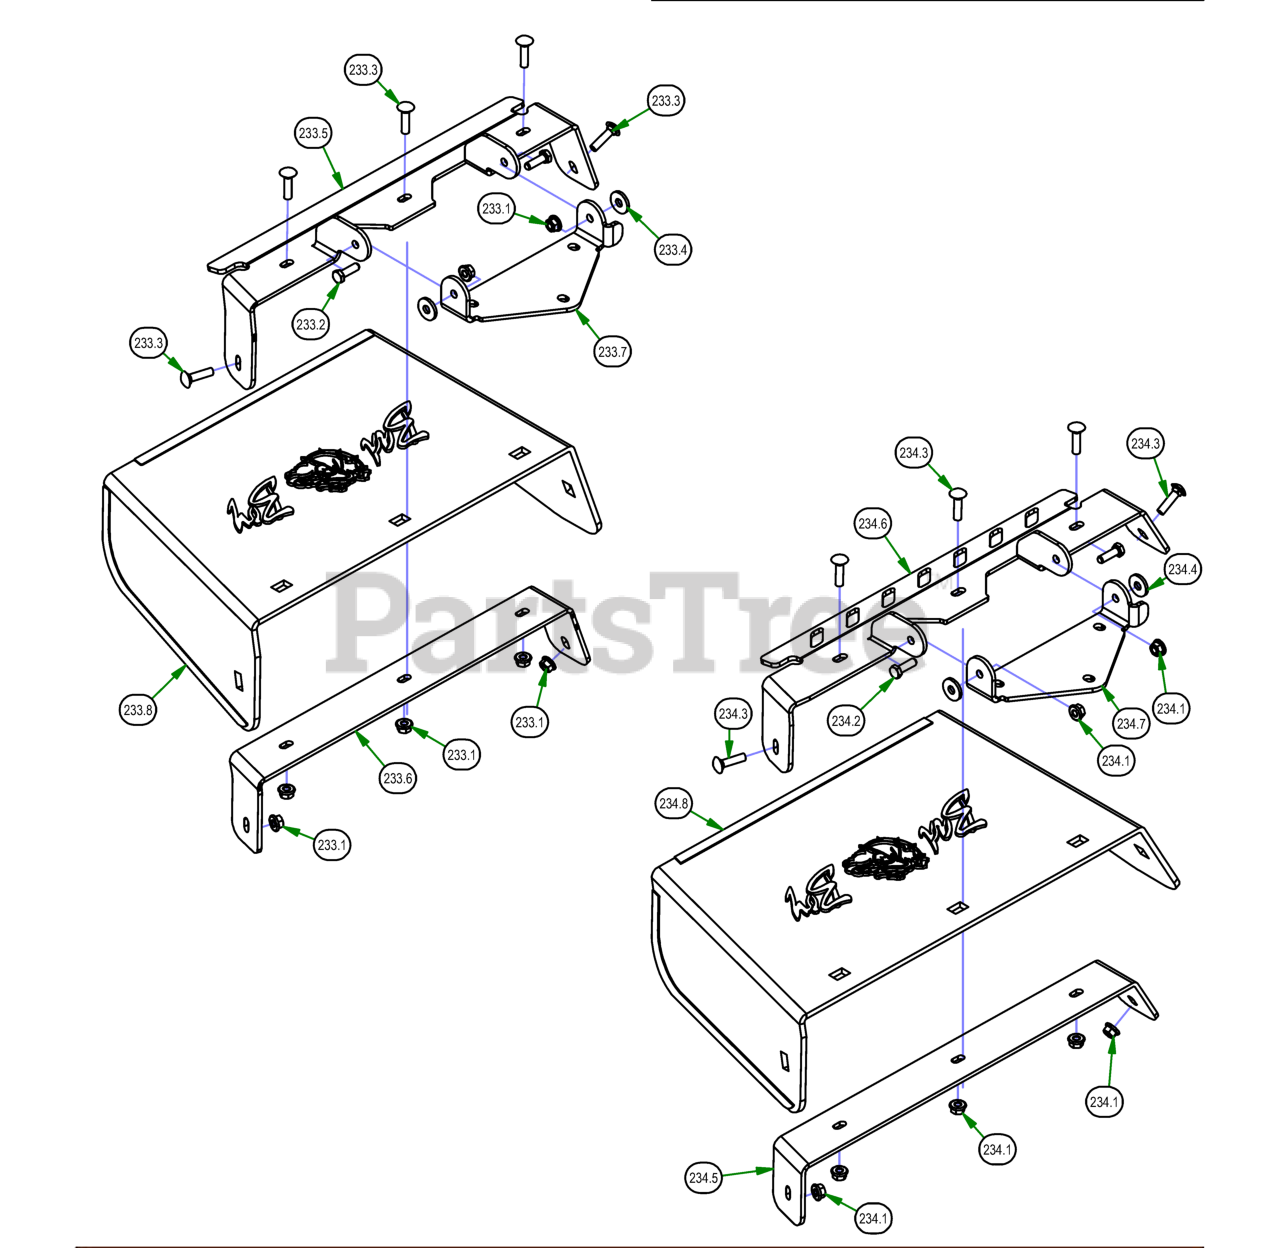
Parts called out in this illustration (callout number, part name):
233	ZT Chute Assembly
233.1	5/16-18 NYLON INSERT FLANGE LOCKNUT ZINC
233.2	5/16-18 X 1 HEX CAP SCREW (GR.5) ZINC
233.3	5/16-18 X 1-1/4 CARRIAGE BOLT ZINC
233.4	.360 ID X .983 OD X .120 THICK FLAT WASHER NYLON
233.5	Discharge Upper Chute Bracket
233.6	Discharge Lower Chute Bracket
233.7	Discharge Chute Hanger (deck mounted)
233.8	Rubber Discharge Chute
234	Discharge Chute Assembly
234.1	5/16-18 NYLON INSERT FLANGE LOCKNUT ZINC
234.2	5/16-18 X 1 HEX CAP SCREW (GR.5) ZINC
234.3	5/16-18 X 1-1/4 CARRIAGE BOLT ZINC
234.4	.360 ID X .983 OD X .120 THICK FLAT WASHER NYLON
234.5	60" Discharge Lower Bracket
234.6	60" Discharge Chute Upper Hanger
234.7	Discharge Chute Hanger (deck mounted)
234.8	Rubber Discharge Chute
